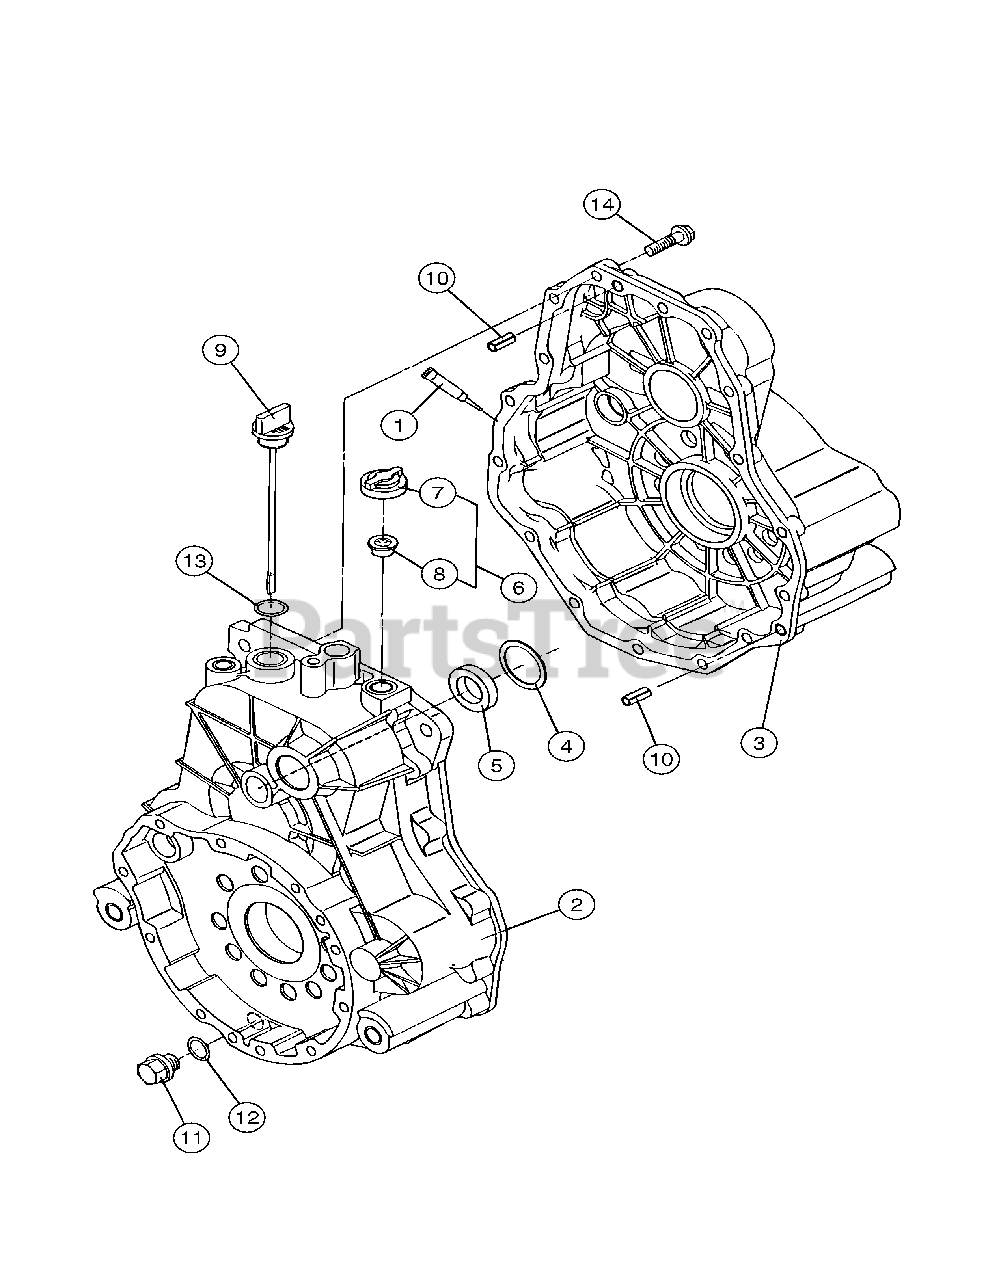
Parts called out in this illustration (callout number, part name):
1	Sealant
2	Housing, Transaxle, Left
3	Housing, Transaxle, Right
4	Washer, 36 x 45.5 x 1.2
5	Seal, TC 30 40 8
6	Vent Valve
7	Cap, Vent Valve
8	Body, Vent Valve
10	Pin, 8 x 20
11	Plug, 14
12	Packing, P 16
13	Packing, P 18
14	Bolt, 28 x 10 x 9
